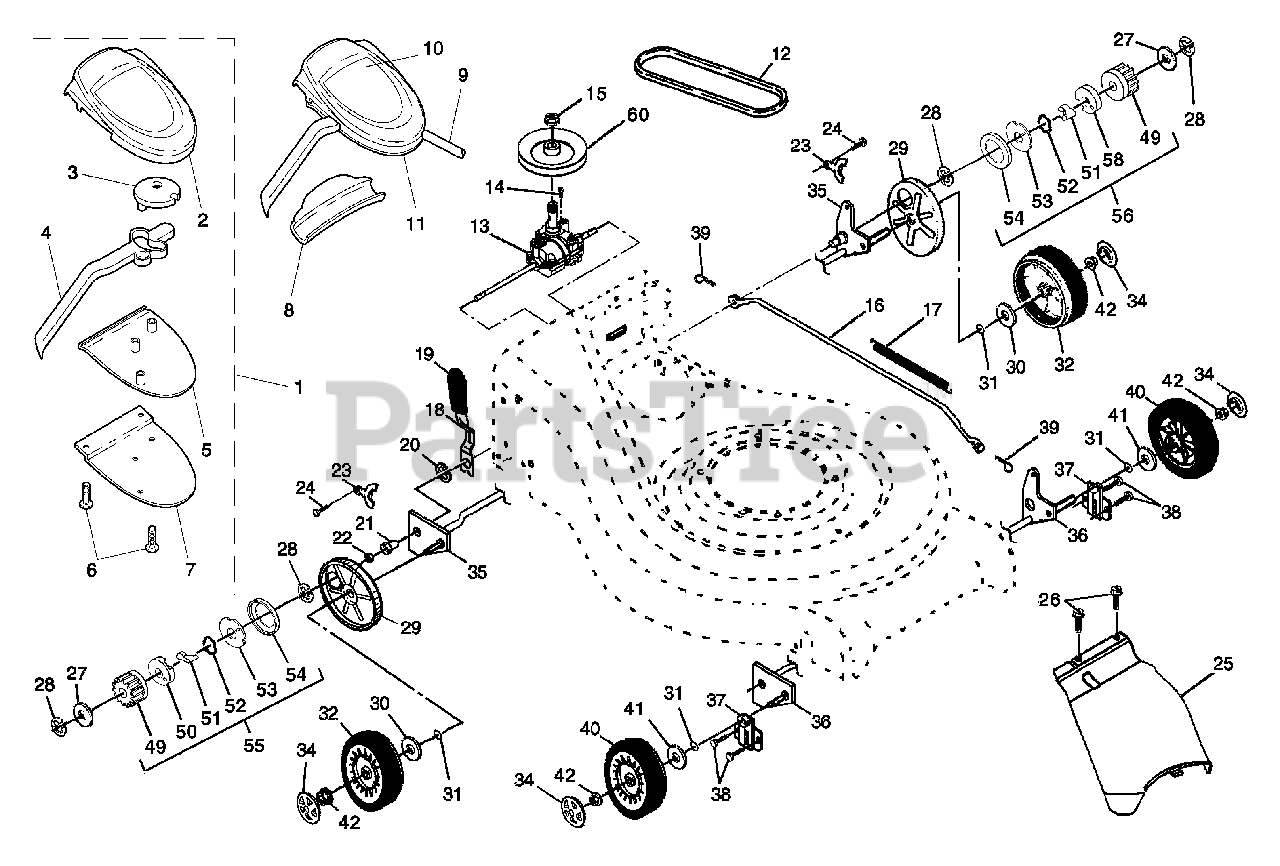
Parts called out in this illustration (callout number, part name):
1	Drive Control Assembly, Auto-Walk
2	Cover, Top, Auto-Walk Drive Control
4	Lever, Auto-Walk Drive Control
5	Cover, Bottom, Auto-Walk Drive Control
6	Screw, Phillips Head #10 x 5/8
7	Plate, Trigger, Auto-Walk Drive Control
8	Cap, Drive Control, Bottom
9	Cable, Drive Control
10	Decal, Drive Control
11	Decal, Drive Control Adjustment (bottom)
12	V-Belt
13	Gear Case Assembly
15	Nut, Hex, Flanglock, Zinc Plated 3/8-16
16	Rod, Connecting
17	Spring, Extension
18	Spring Selector
19	Knob, Selector Spring
21	Bearing, Support
22	Bearing, Ball
23	Retainer, Drive Assembly, Stamped
24	Screw, Tapping, Hex Head 1/4-20 x .75
25	Cover Drive
26	Screw, Threaded, Rolled #10-25 x .50
28	E-Ring 7/16
29	Cover, Dust, Wheel
30	Washer 1/2 x 1-1/2 x .134
31	O-Ring
32	Wheel 9 x 2
34	Hubcap
35	Shaft Assembly, Rear
36	Shaft Assembly, Front
37	Retainer, Front Shaft
38	Screw #12 x 5/8
39	Clip, Retainer
40	Wheel 8 x 2
41	Washer, Flat 3/8
42	Nut, Hex, Flangelock 3/8-16
49	Gear, Pinion
50	Retainer, Drive, RH
52	Spring, Torsion
53	Disc, Drive
54	Seal, Friction
55	Pinion Assembly, RH
56	Pinion Assembly, LH
58	Retainer, Drive, LH
60	Pulley, Drive
